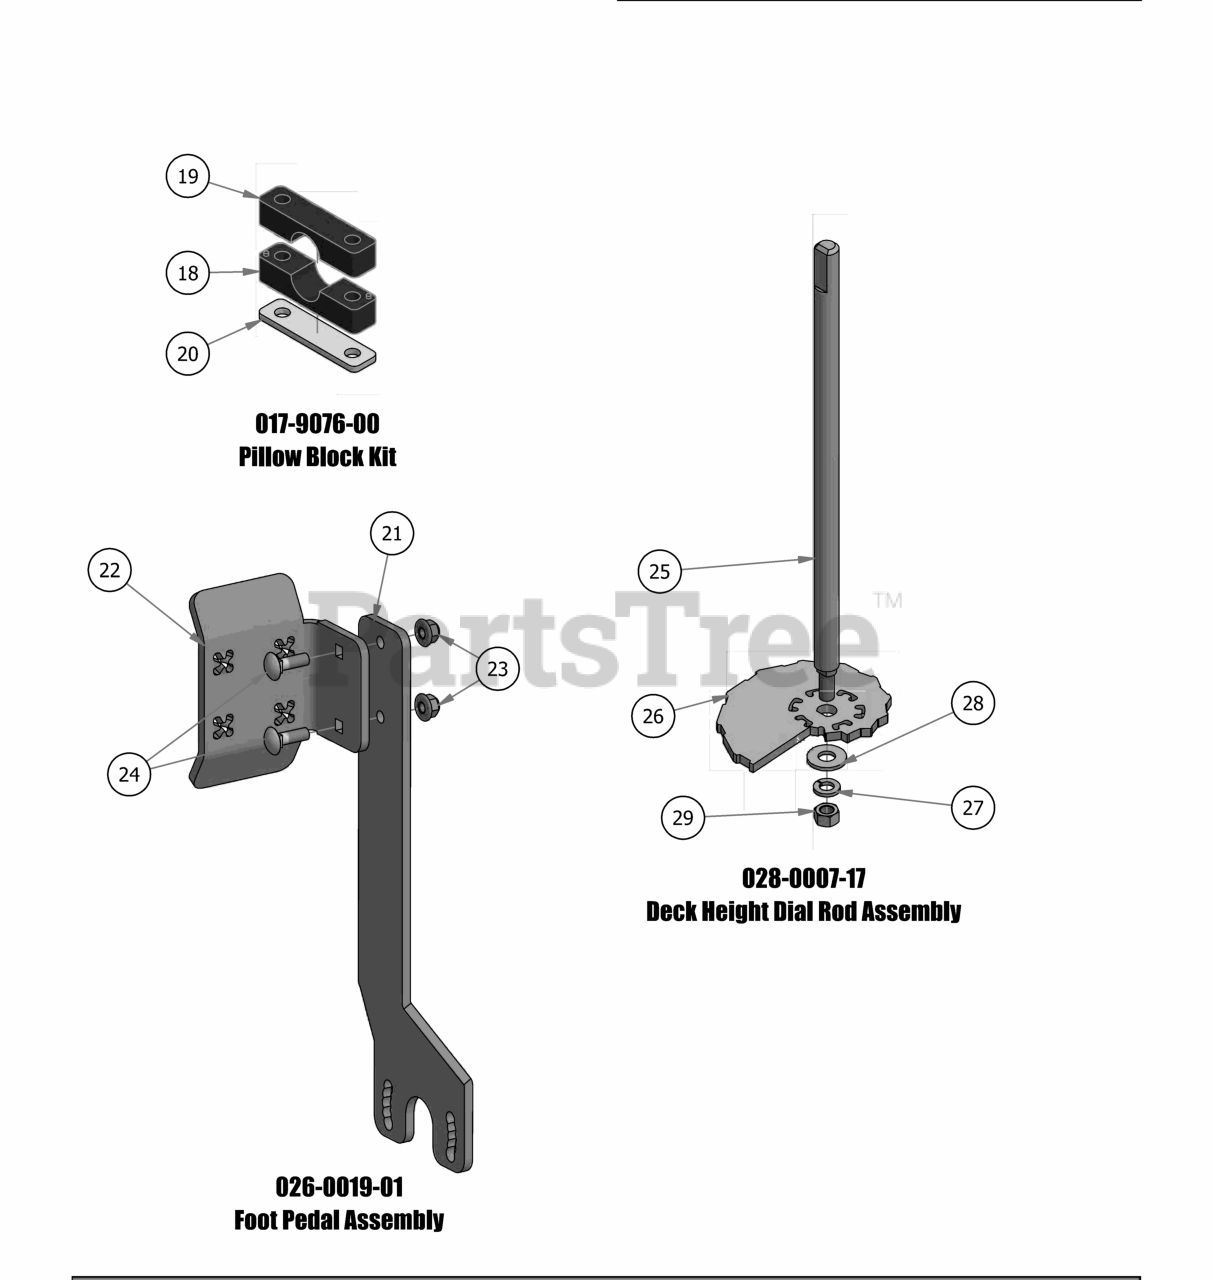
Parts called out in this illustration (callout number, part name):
18	Pillow Block MZ male
19	Pillow Block MZ female
20	Pillow Block Strap
21	2017 MZ/ZT Deck Pedal Lever
22	2017 MZ/ZT Shallow Foot Pedal
23	5/16" Nylon Flange Nut
24	5/16" x 1" Carriage Bolt
25	2017 Deck Height Dial Rod MZ
26	2017 MZ/ZT Cam Plate
27	3/8" Lock Washer
28	3/8" Flat Washer
29	3/8" Fine Threaded Jam Nut
